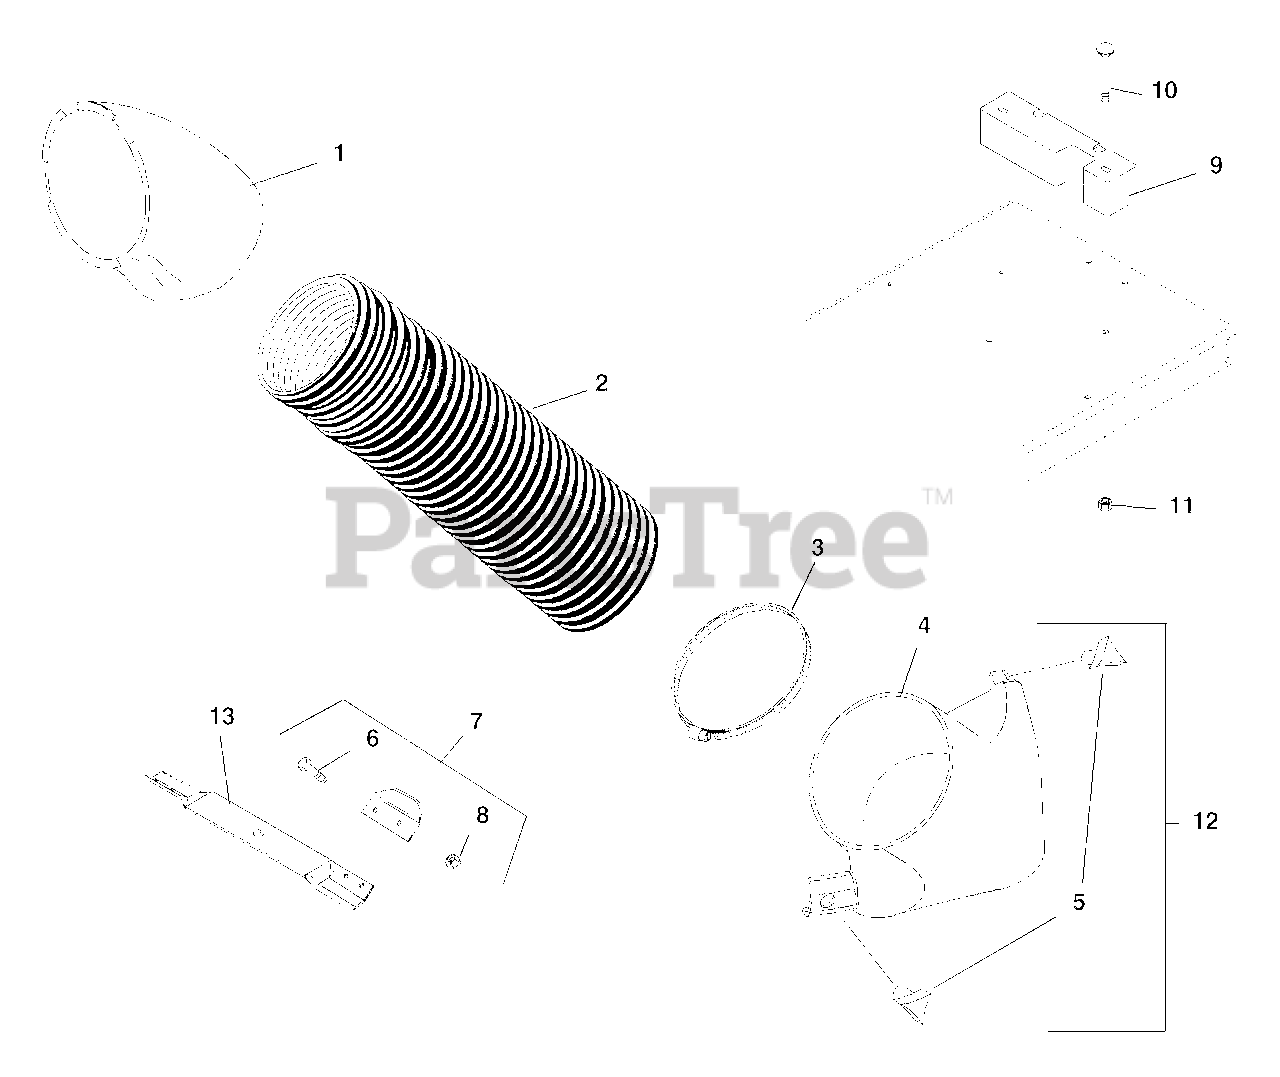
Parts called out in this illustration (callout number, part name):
1	Upper Boot
2	Hose 7 x 45
3	Hose Clamp
4	Mower Boot Assembly with Decal
6	Bolt-Hex .31-24 x .75 Grade 8
7	Vane Service Assembly
8	Nut-Locking Top .312-24
9	Counterweight
10	Bolt-Round Head Square Neck .44 -14 x 4.50 Grade 2
11	Nut .437-14
12	Mower Boot Assembly - 42"
13	22" Blade
